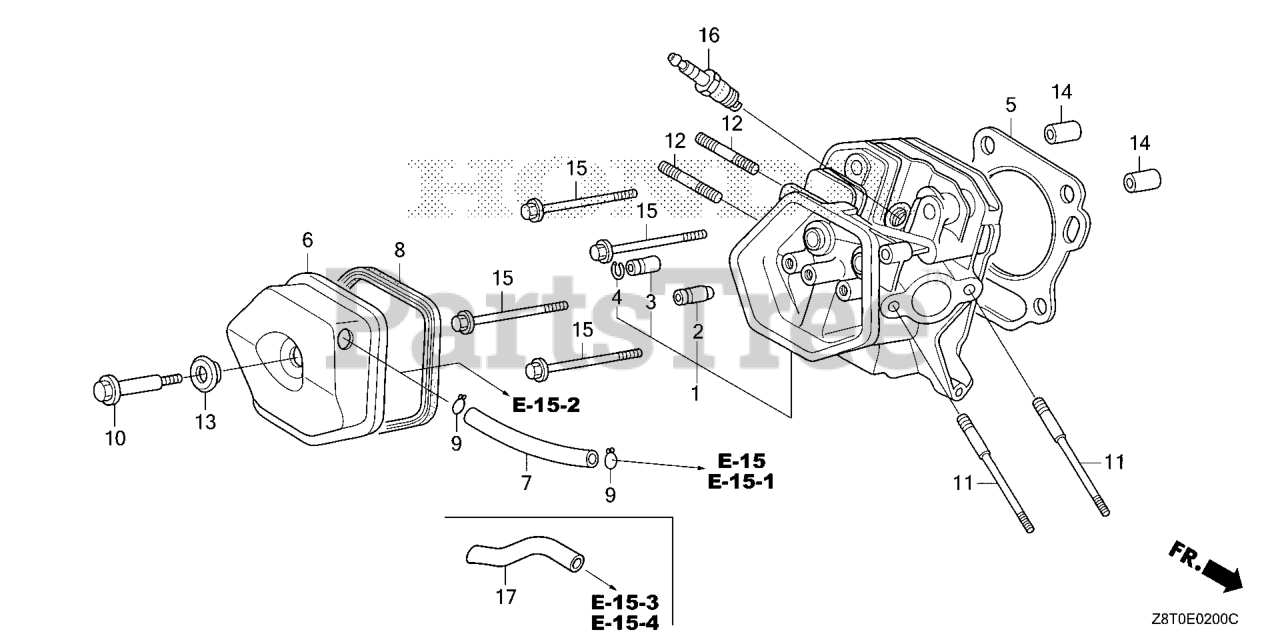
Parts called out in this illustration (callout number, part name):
1	CYLINDER HEAD
4	CLIP, VALVE GUIDE
5	GASKET, CYLINDER HEAD (NIPPON LEAKLESS)
6	COVER, HEAD
8	GASKET, CYLINDER HEAD COVER
10	BOLT, HEAD COVER
11	BOLT, STUD (8X131.5)
12	BOLT 2, STUD (8X32)
13	WASHER, HEAD COVER
14	PIN A, DOWEL (12X20)
15	BOLT, FLANGE (10X80)
16	SPARK PLUG (BPR5ES) (NGK)
16	SPARK PLUG (W16EPR-U) (DENSO)
16	SPARK PLUG (BPR6ES) (NGK)
17	TUBE, BREATHER
